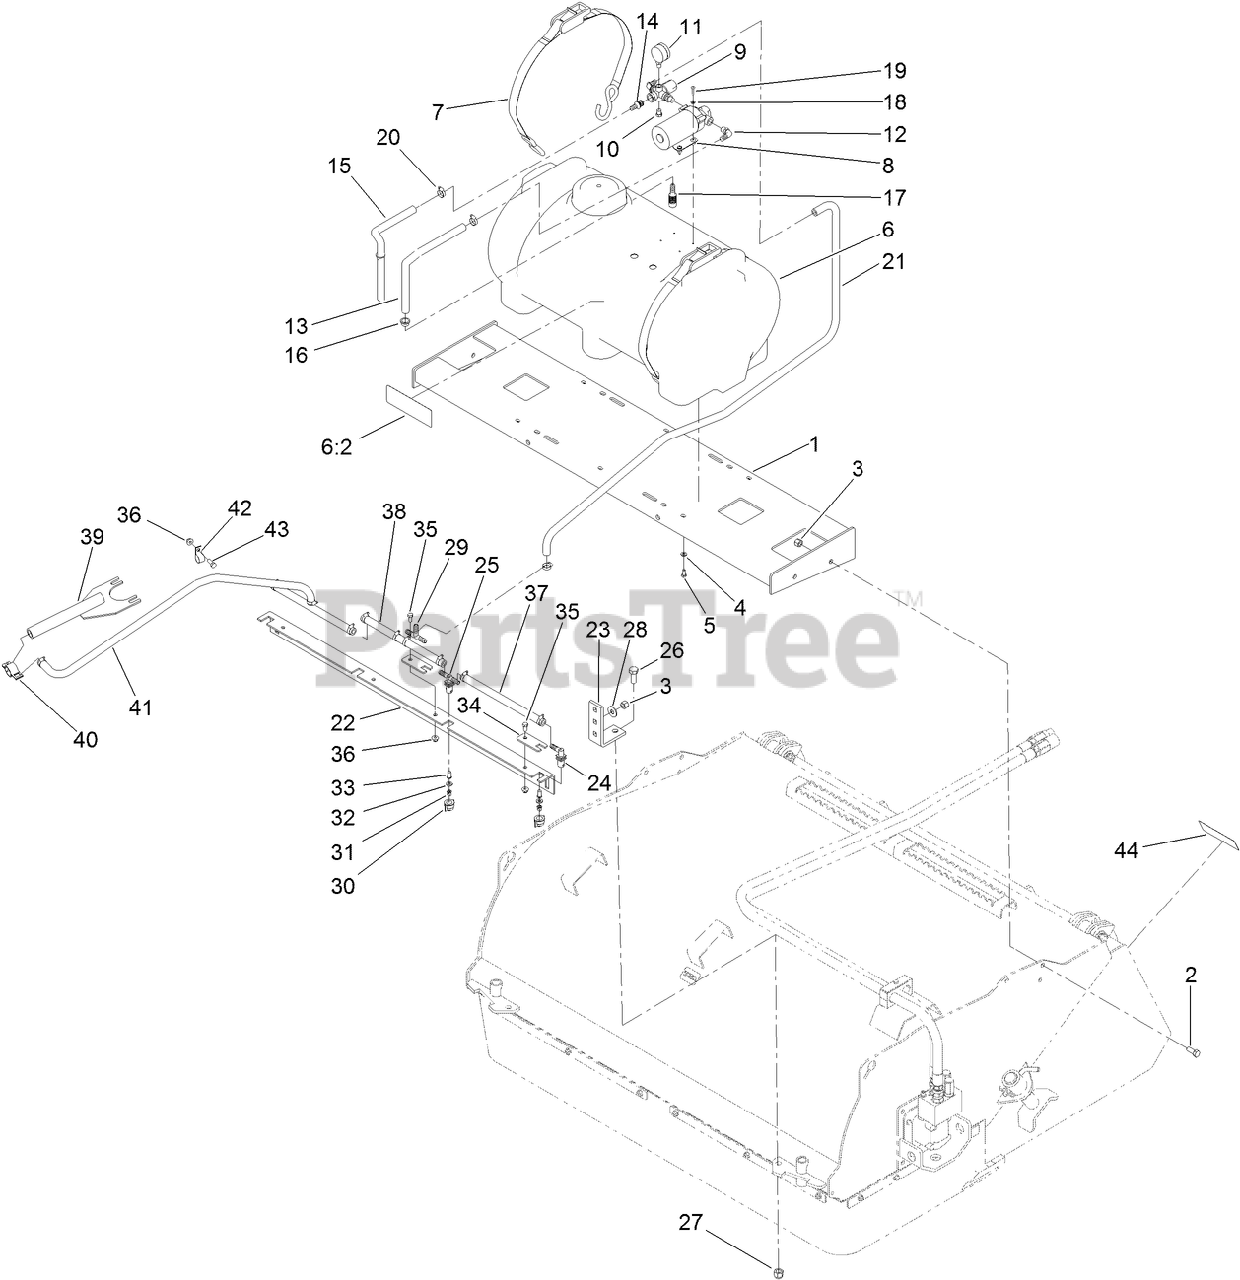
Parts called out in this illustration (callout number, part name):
1	MOUNT-TANK
2	SCREW-HH
3	NUT-LOCK, NI
4	WASHER-PLAIN
5	SCREW-HH
6	TANK-WATER
6:2	DECAL-WARNING
7	STRAP-RATCHET
9	REGULATOR-PRESSURE
10	PLUG-HYD
11	GAUGE-PRESSURE
12	FITTING-ELBOW
13	HOSE-WATER
14	FITTING-STRAIGHT
15	HOSE-WATER
16	GROMMET-HOSE
17	STRAINER
18	WASHER-FLAT
20	CLAMP-HOSE
21	HOSE-WATER
22	MOUNT-NOZZLE
23	BRACKET-BAR, SPRAY
24	ELBOW-BARBED
25	TEE-BARBED
26	SCREW-HH
27	NUT-LOCK, NI
28	WASHER-FLAT
29	T-BARBED
30	CAP-NOZZLE, SPRAY
31	NOZZLE-SPRAY
32	GASKET
33	SCREEN
34	RETAINER-NOZZLE
35	SCREW-HH
36	NUT-HF, NI
37	HOSE-WATER
38	HOSE-WATER
39	MOUNT-NOZZLE
40	CLAMP-NOZZLE, SPRAY
41	HOSE-WATER
42	CLAMP-HOSE
43	SCREW-HH
44	DECAL-WARNING, CAPACITY
